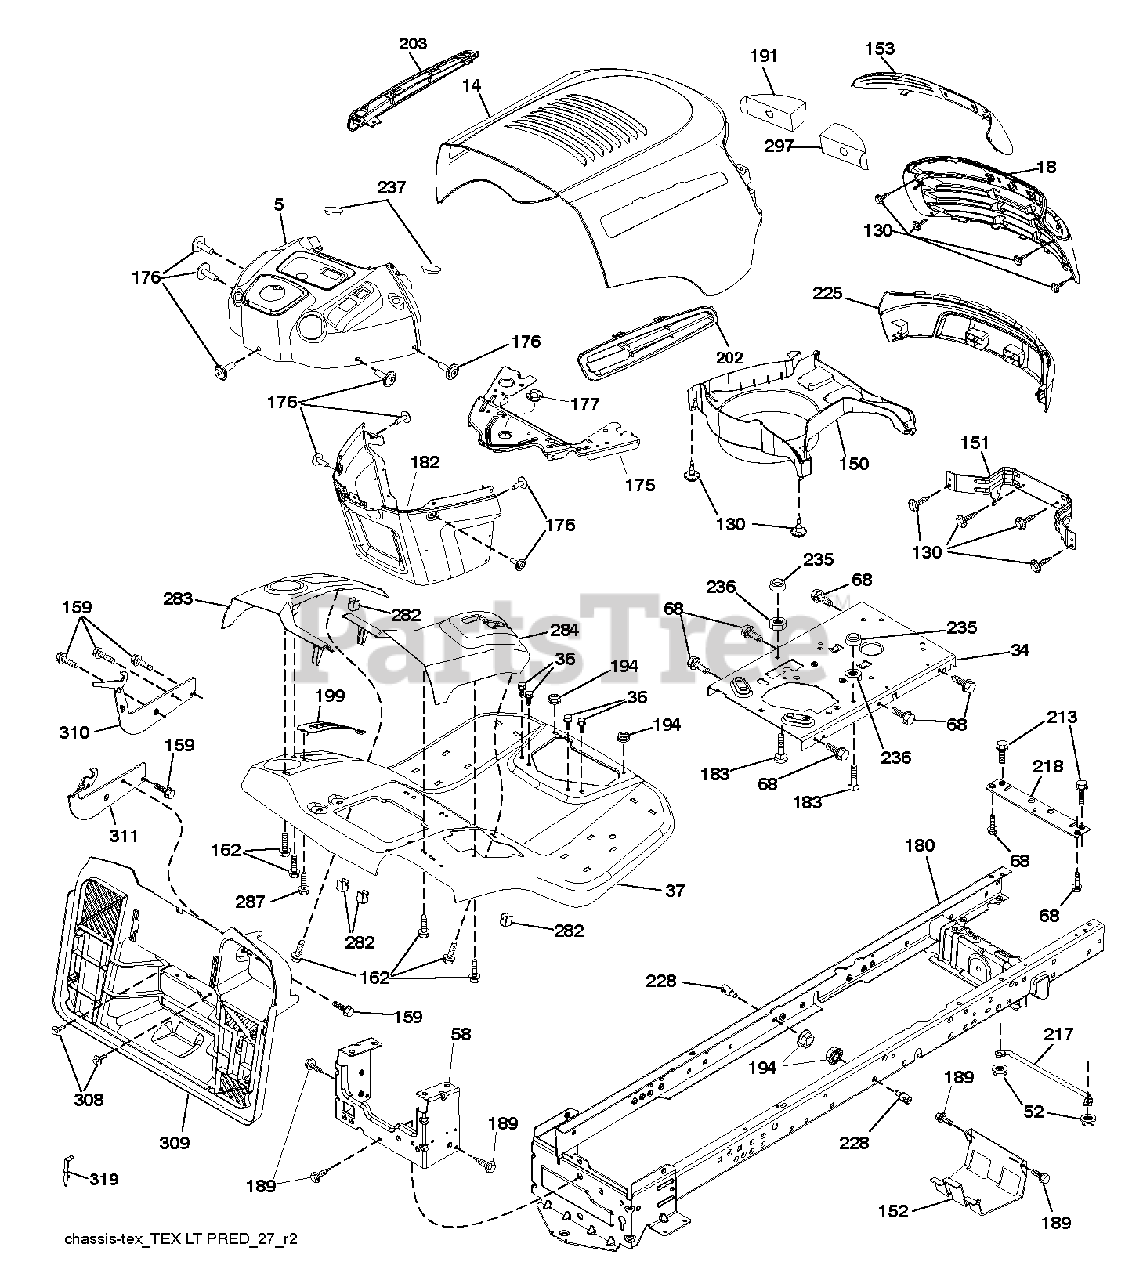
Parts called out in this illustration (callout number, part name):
5	DASH.PRED.LT.CC.ICY.SRVMDR.BLK
34	PLATE.ENGINE.WELDED.CHASSIS
36	SCREW 5/16"
52	LOCKNUT
58	DRAWBAR UPPER 2PC SMALL FENDER
130	SCREW.#10 X 0.750.BOS THREAD
151	BRACKET.PIVOT.ALPHA.LT
152	SHIELD BROWNING
159	SCREW, 3/8-16X3/4
162	SCREW.HI-LO.CONSOLE
175	CROSSMEMBER
176	SCREW.#10-24X5/8.RN.QU
177	BUSHING STEERING
182	DASH.LWER.PREDATOR/HUSQ.LT
183	BOLT.5/16-18X1-1/4 FULL.THREAD
189	SCREW
191	REFLECTOR.INSERT.PRED.LH.LT
194	NUT LOCK HEX FLANGE 5/16-18
213	BOLT
217	ROD.PIVOT.HOOD
218	X-PIECE.HOOD.STOP.NON/
228	STUD.FASTNER.W/ANTI-ROTATE
235	SPACER FENDER
236	NUT.CENTERLOCK.5/16-
237	PLUG.MOUNT.CARGO.BLK
282	CLIP.RETAINER.CONSOLE.LT.HUSQ
297	INSERT.REFLECT.PREDATOR.LT.RH
308	BOLT, 5/16-18 X 1 3/4
